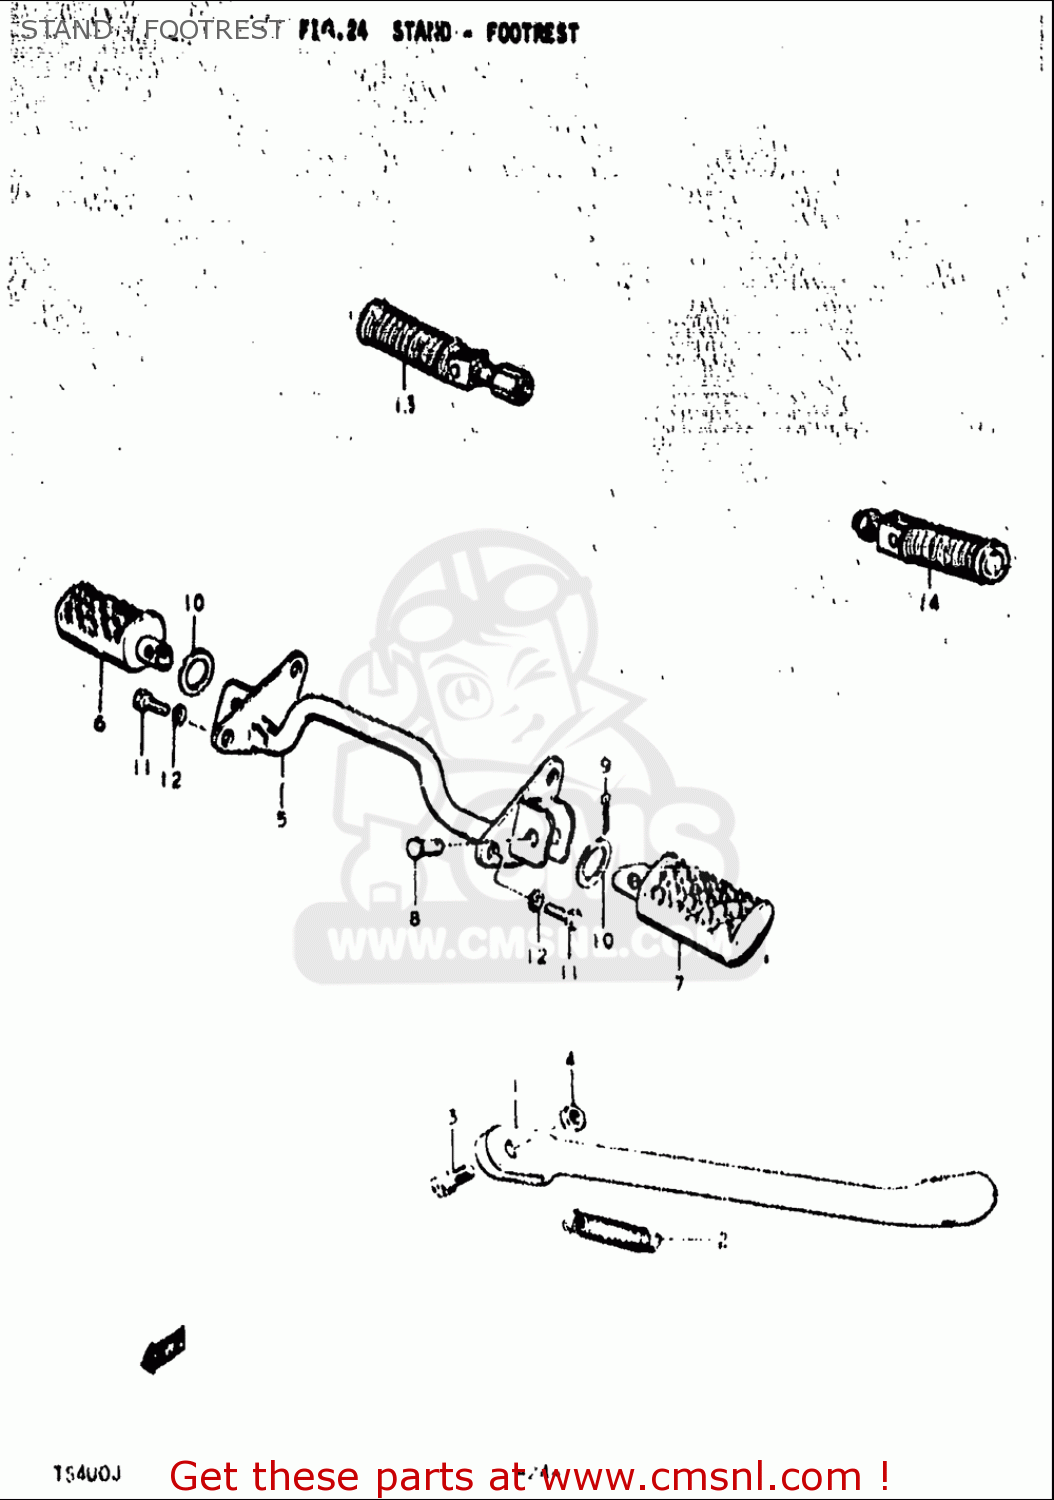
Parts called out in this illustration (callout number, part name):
2	SPRING
3	BOLT(10X30)
4	NUT
8	PIN
9	PIN
10	WASHER(22.5X38X1)
11	BOLT
12	WASHER,LOCK
14	FOOTREST ASSEMBLY,REAR
